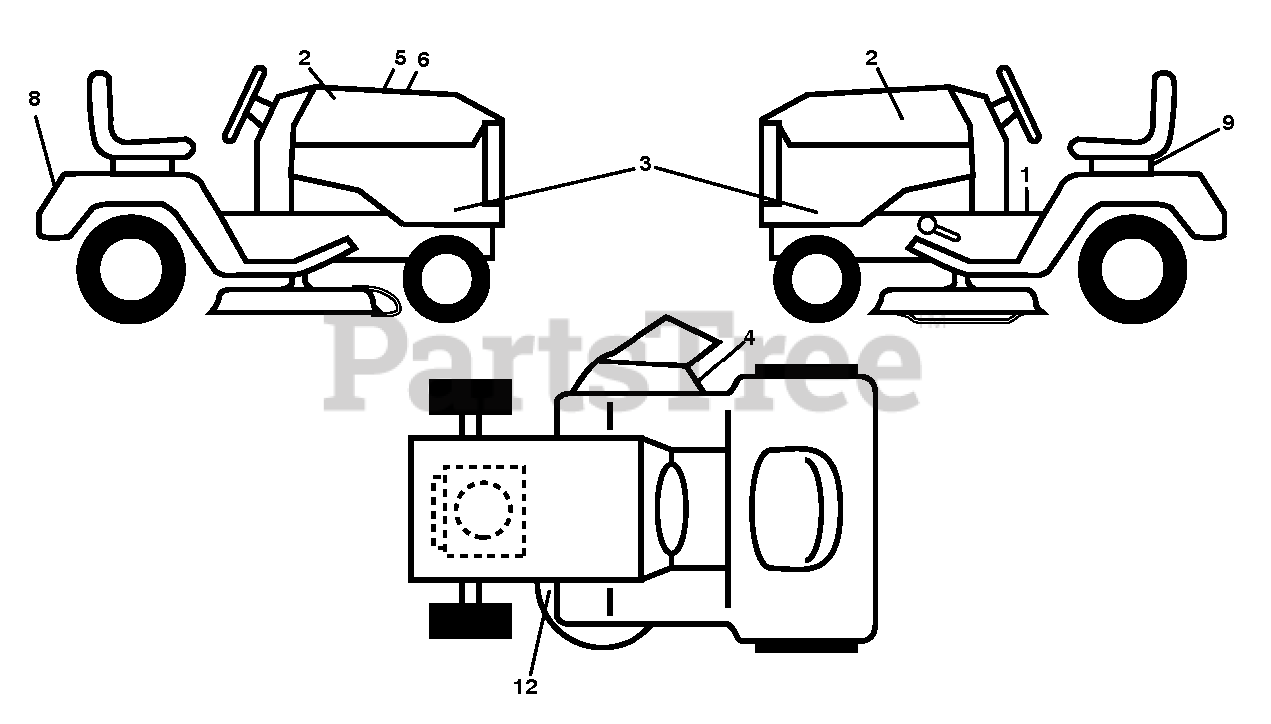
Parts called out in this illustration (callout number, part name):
1	DECAL.WARN.START.INSTRUCTIONS
2	DECAL.BADGE.170MM.TEXTLOGO.
3	DECAL.SDPNL.HUSQGT2.YTH12K26.2
4	DECAL.WARN.KEEP.HAND.AWAY
5	DECAL.WARNING.CUST.RESP.E85.
6	DECAL.REPLACEMENT.960450026
8	DECAL.FENDER
9	DECAL BTRY SYMBOLS
12	DECAL V BELT SCHEMATIC
